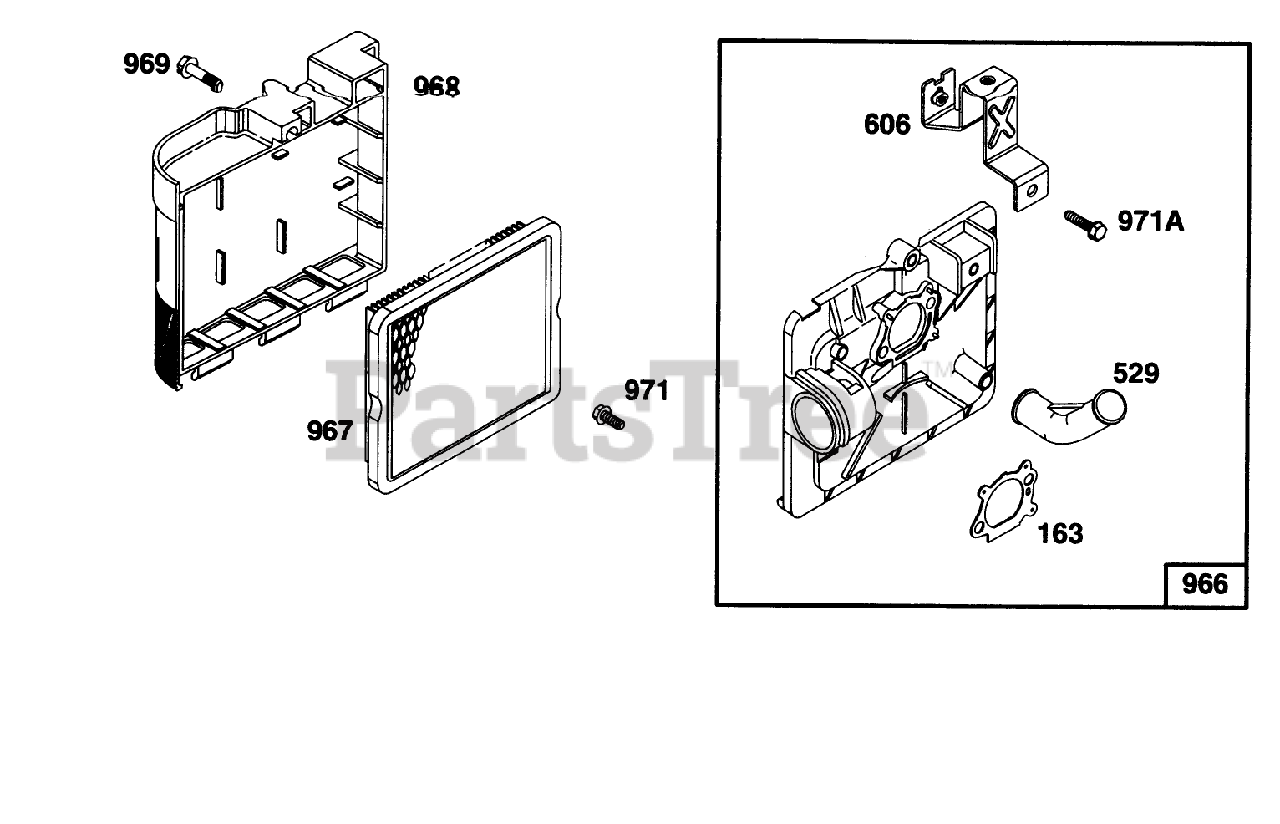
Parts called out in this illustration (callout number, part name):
163	Gasket-Cleaner, Air
529	Grommet
606	Strap-Bracket
966	Base-Primer, Air Cleaner
967	Filter-Air Cleaner, Cartridge
968	Air Cleaner Cover
969	Screw-Cover Mt.
971	Screw-Air Cleaner
971A	Screw-Hex.
